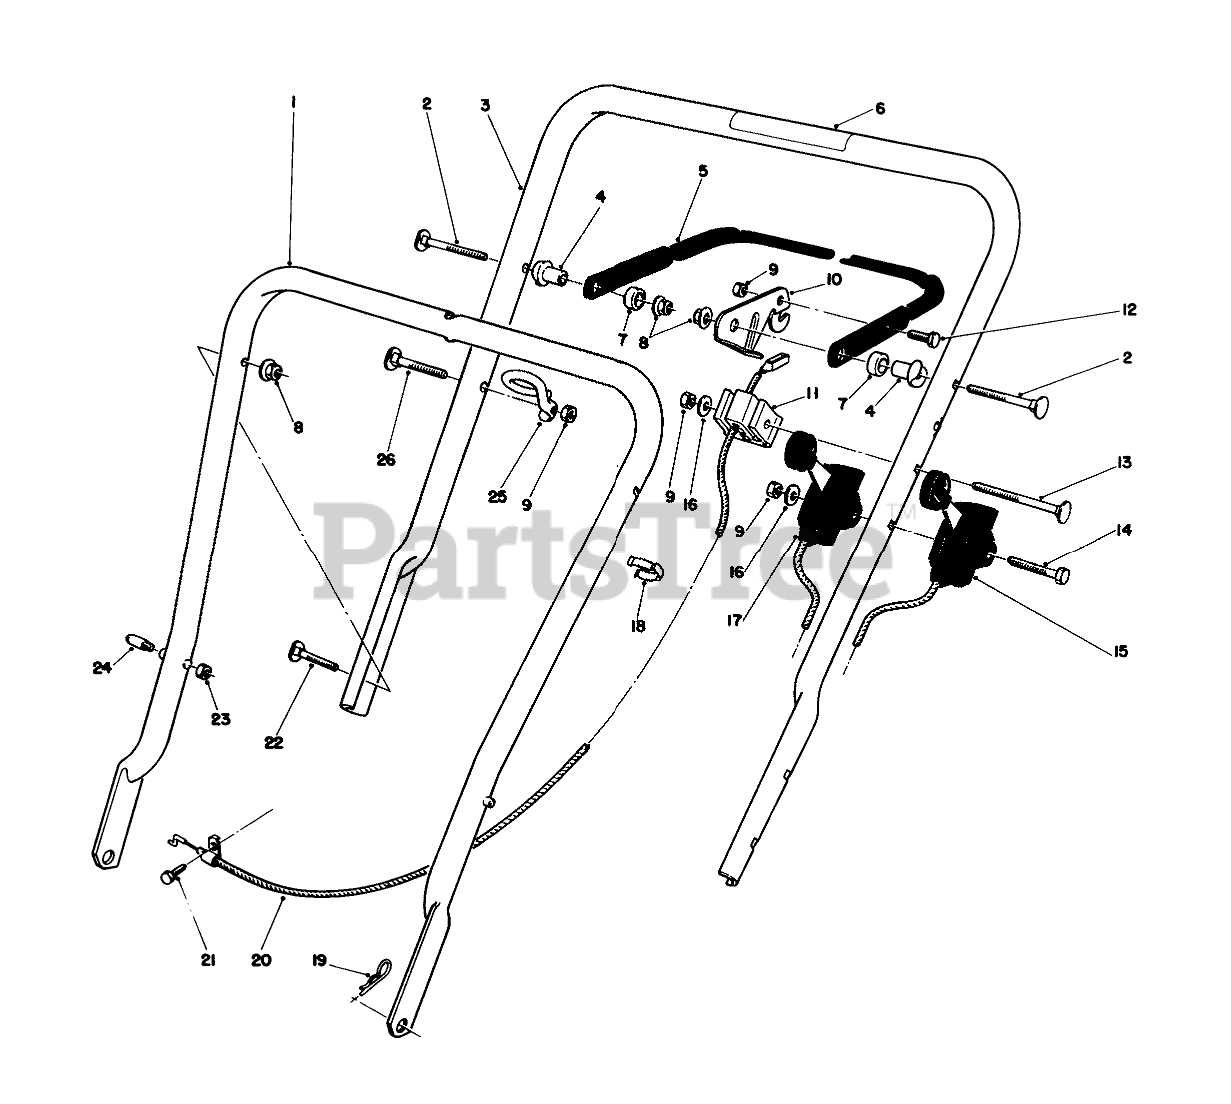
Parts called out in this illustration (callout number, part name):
1	LOWER HANDLE ASM
2	5/16-18 X 2 HNDLE SCREW
3	Handle-Upper (Incl. Ref. #6)
4	SPACER-SUPPORT
5	CONTROL BAR PROMO
6	Decal-Danger
7	SPACER-NYLON
8	NUT-LOCK, NI
9	NUT-LOCK, NI
10	Lever-Control
11	SUPPORT-CABLE
12	SCREW-HH
13	HANDLE SCREW
14	SCREW-HH
15	Control-Traction (Bend Type #3)(Sheath Lg. 46")(WireLg. 1-1/4")
16	WASHER-FLAT
17	SERVICE THROTTLE CONTRO
18	BOWDEN CLIP
19	PIN-COTTER, HAIR
20	BRAKE CABLE
21	SCREW-HH
22	SCREW
23	NUT-LOCK, NI
24	HANDLE PIN
25	Guide
26	HANDLE SCREW
